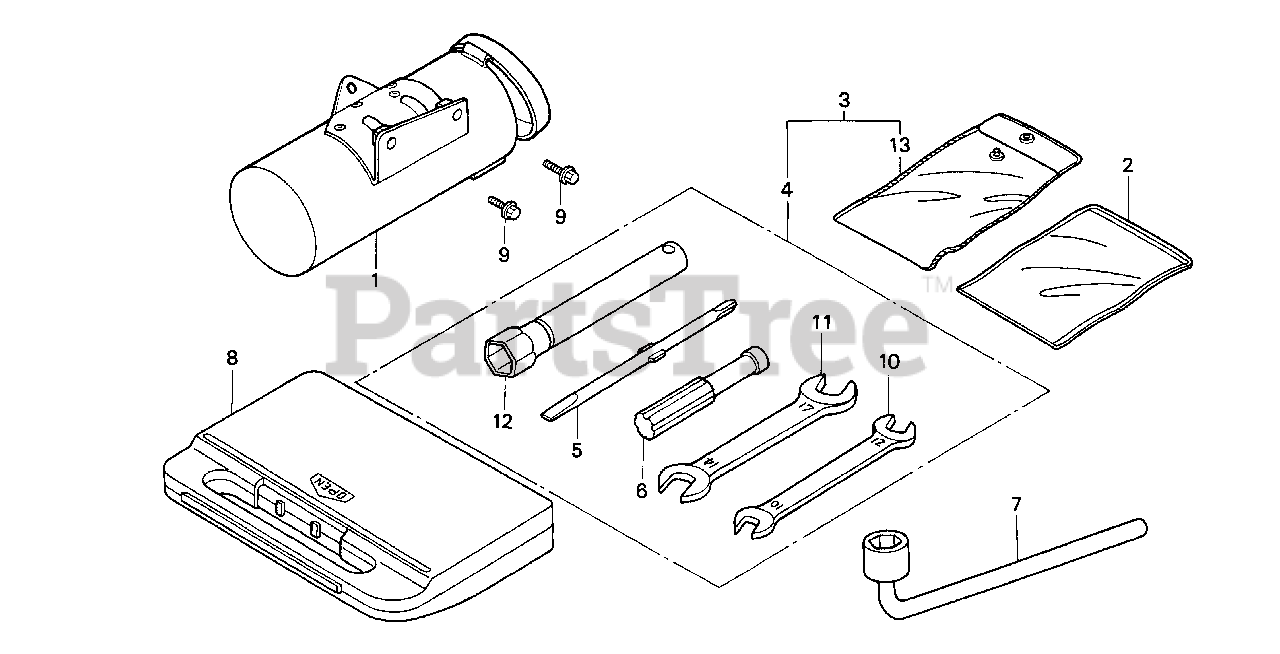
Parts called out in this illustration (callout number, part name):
1	BOX ASSY., TOOL
2	BAG, OWNER'S MANUAL
5	SCREWDRIVER (NO.2 PHILLIPS -)
7	WRENCH, WHEEL NUT
9	BOLT, FLANGE (6X16)
10	SPANNER (10X12)
11	SPANNER (14X17)
12	WRENCH, BOX (P21)
